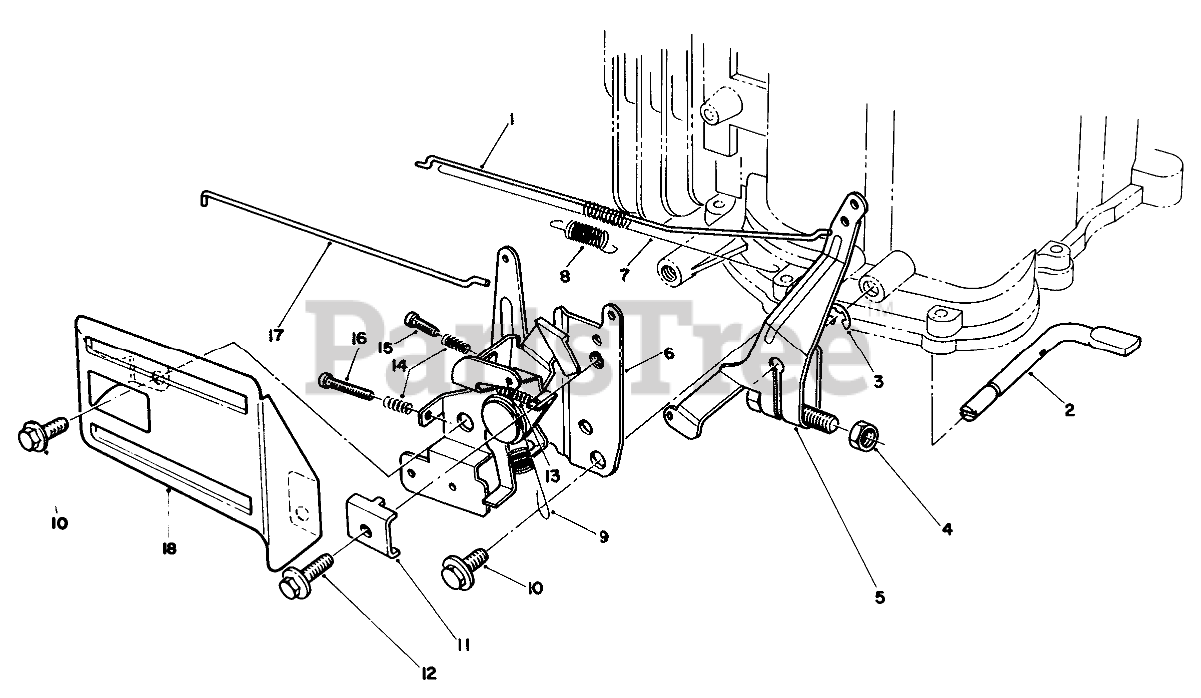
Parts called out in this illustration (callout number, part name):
1	Rod-Carburetor
2	SHAFT
3	E-RING
4	Nut
5	ARM ASM
6	THROTTLE
7	SPRING
8	SPRING
9	SPRING
11	CLAMP-CABLE
13	SPRING
14	SPRING
15	SCREW
16	SCREW
17	Rod-Choke
18	THROTTLE GUARD
